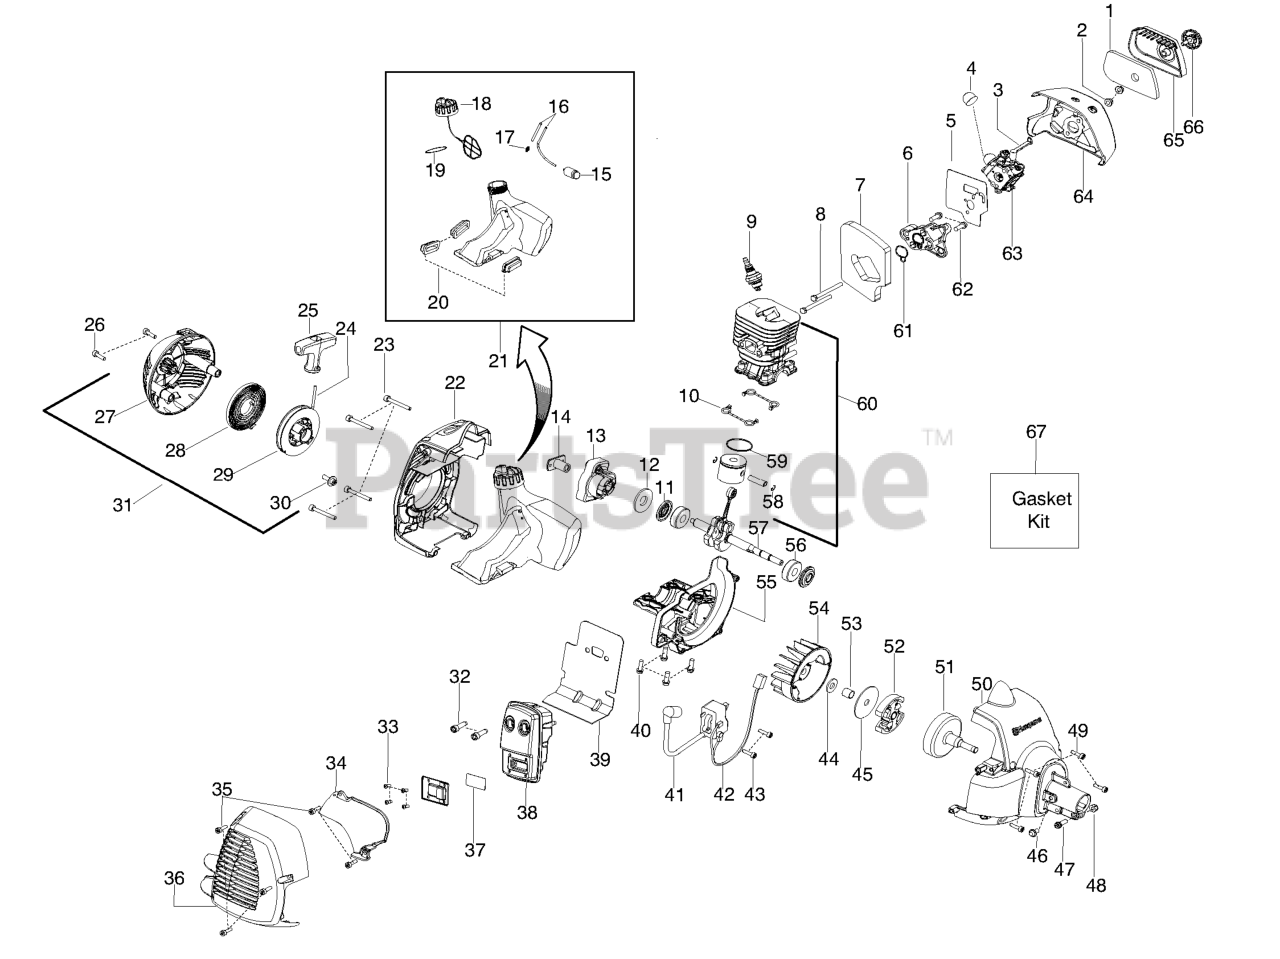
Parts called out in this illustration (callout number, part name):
2	Nut - Carb. Screw
3	Lever - Choke
4	Bulb - Purge
5	Kit-Carb. Gasket
6	Adaptor - Carb.
7	Foam - Gasket (kit)
9	Plug - Spark (RCJ-6Y)
10	Seal - Cylinder (kit)
11	Seal - Crankshaft (kit)
12	Washer
13	Assy - Starter Cup
14	Coupling - Starter
15	Assy - Fuel Filter
16	Kit - Fuel Line
17	Fitting - Fuel Line
18	Assy - Cap w/ret.
19	O-Ring - Fuel Cap (kit)
20	Isolator - Fuel Tank
21	Kit - Fuel Tank
22	Shroud - Rear
24	Kit - Rope
25	Handle - Starter
27	Starter Hsg. w/eyelet
28	Kit - Starter Spring
29	Kit - Starter Pulley
31	Assy-Starter Hsg.
32	Bolt - Muffler
33	Screw
34	Shield - Heat
36	Guard - Muffler
37	Kit - Spark
38	Kit - Muffler
39	Gasket-Paper Met.(kit)
41	Module
42	Assy - Leadwire
45	Washer - Clutch
50	Assy - Fan Housing
51	Assy - Clutch Drum
52	Kit - Clutch Assy.
55	Crankcase - cast
57	Crankshaft - Assy
58	Retainer - Piston Pin
59	Ring - Piston
60	Kit - Cyl./Piston
61	Seal - adaptor (kit)
63	Kit - Carb.
64	Airbox
65	Cover - Air Box
66	Assy - Knob
67	Kit - Gasket
